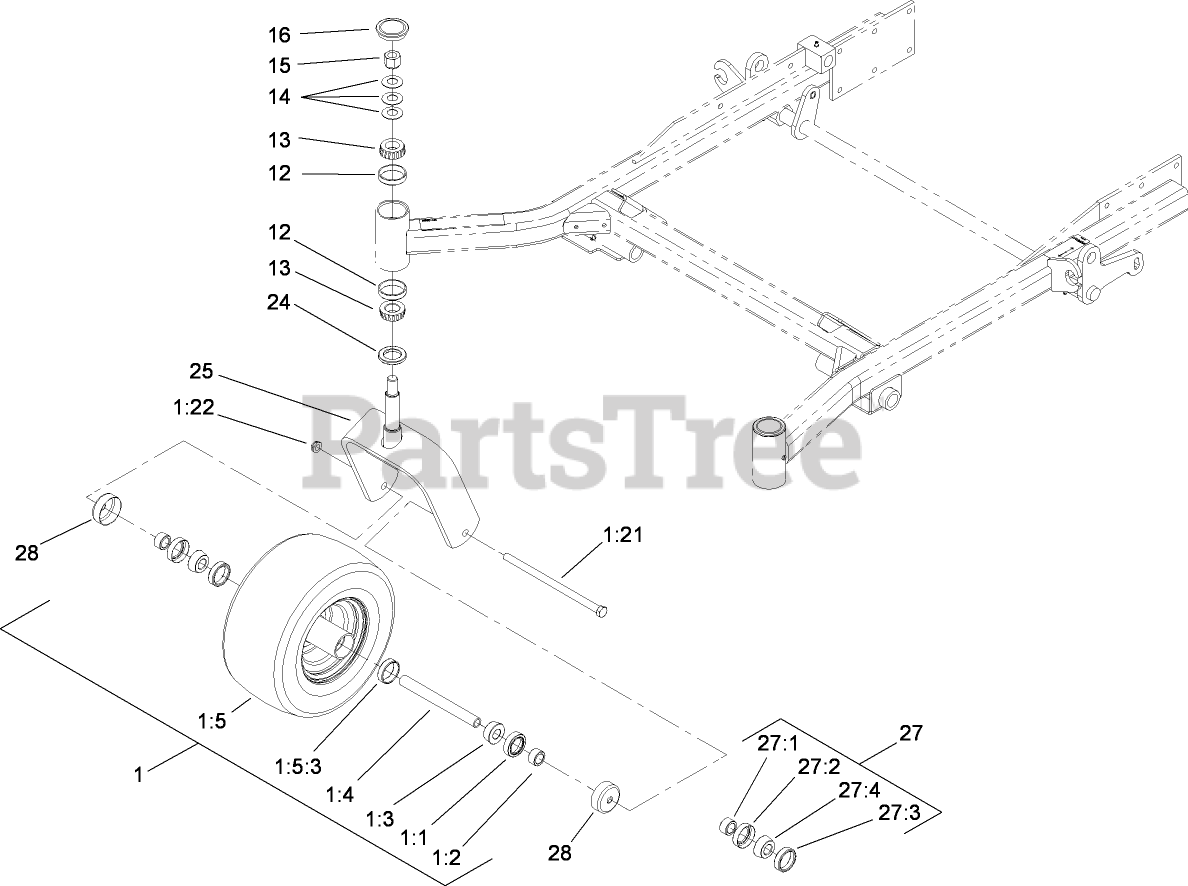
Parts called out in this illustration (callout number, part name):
1	CASTOR WHEEL ASM
1:1	SEAL-BEARING
1:2	SPACER-BEARING
1:3	BEARING-CONE, TAPER
1:4	SPACER-CASTER, FRONT
1:5	WHEEL AND TIRE ASM (SEMI-PNEUMATIC)
1:5:3	BEARING-CUP
1:21	SCREW-HH
1:22	NUT-LOCK, NI
12	BEARING-CUP, TAPERED
13	BEARING-CONE, TAPERED
14	WASHER-BELLVILLE
15	NUT-LOCK, NI
16	CAP-GREASE
24	SEAL-GREASE
25	CASTER-FORK
27	CASTER WHEEL BEARING KIT
27:1	SPACER-BEARING
27:2	SEAL-BEARING
27:3	BEARING-CUP
27:4	BEARING-CONE, TAPER
28	GUARD-SEAL
